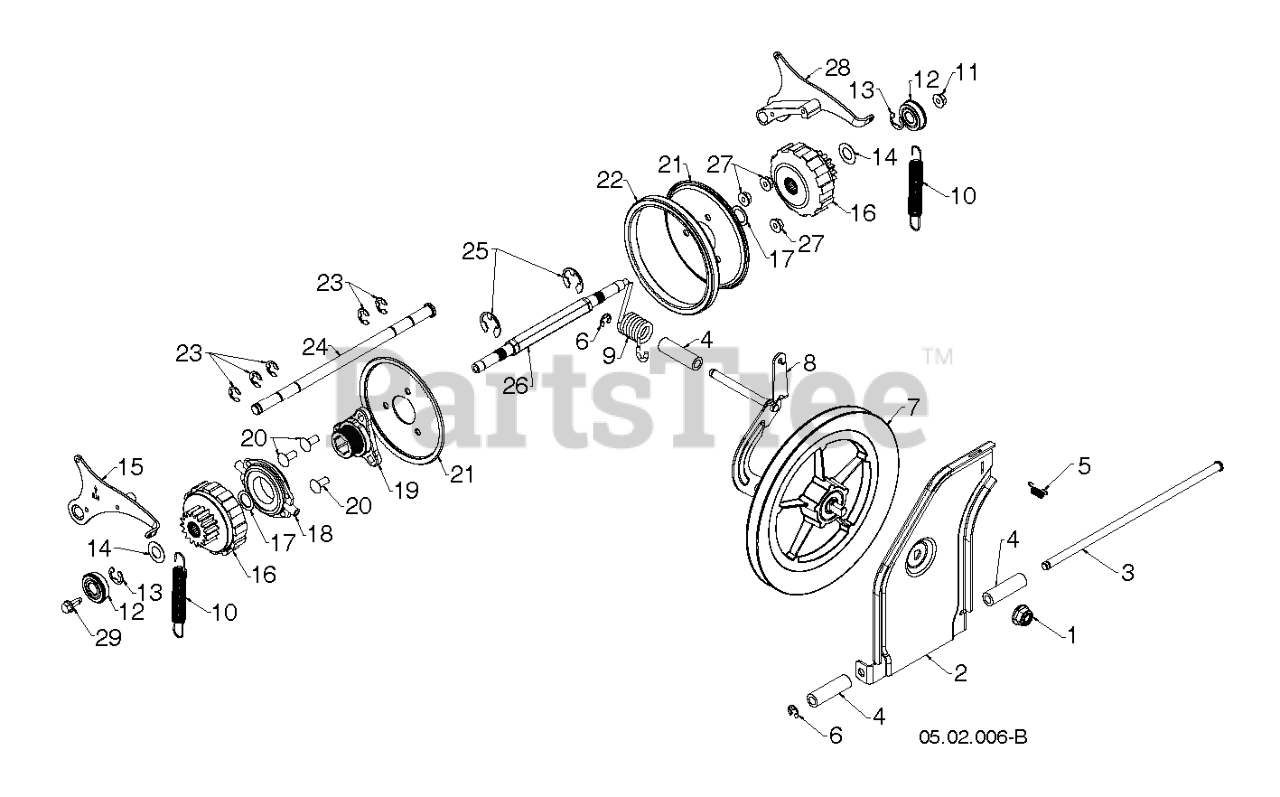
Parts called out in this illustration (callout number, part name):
1	NUT 1/2-13 HEX FLANGE NYLOK CL
3	ROD ROD,PIVOT, SWING PLATE ROD
4	SPACER YOKE, TORSION SPRING
5	SPRING LATCH
6	RETAINER RING E-RING CLEAR ZI
7	PULLEY ASSY TEXTURED TEXTURED
8	BRACKET.YOKE.ASSEMBLY.479
9	SPRING TORSION DRIVE
10	SPRING EXTENSION PS
11	NUT.HEX.FLANGE.LOCK.5/16-18
12	BEARING 9/16 ID. SNR
13	RING.RETAINING.1622-2RSNR.CLER
14	WASHER FLAT.637IDX1.00ODX21GA
15	PAWL.ASM.RH.SNOW
16	GEAR.ASM.PLANETARY
17	WASHER FLAT.59IDX1.065ODX25GA
18	TRUNNION BEARING ASSY
19	HUB.RUBBER.WHEEL
20	BOLT.CARR.SQNK.5/16-18UNC.X3/4
21	PLATE.RUBBER.WHEEL.BLACK
22	Friction Drive
23	CLIP E-RING_.500 SHAFT
24	ROD ROD, PAWL ROD
26	SHAFT SHAFT, PWR STR SHAFT
27	NUT.LOCK.5/16-18
28	PAWL.ASM.LH.SNOW
29	SCREW HEXAGON HEAD FLANGE 5/16
